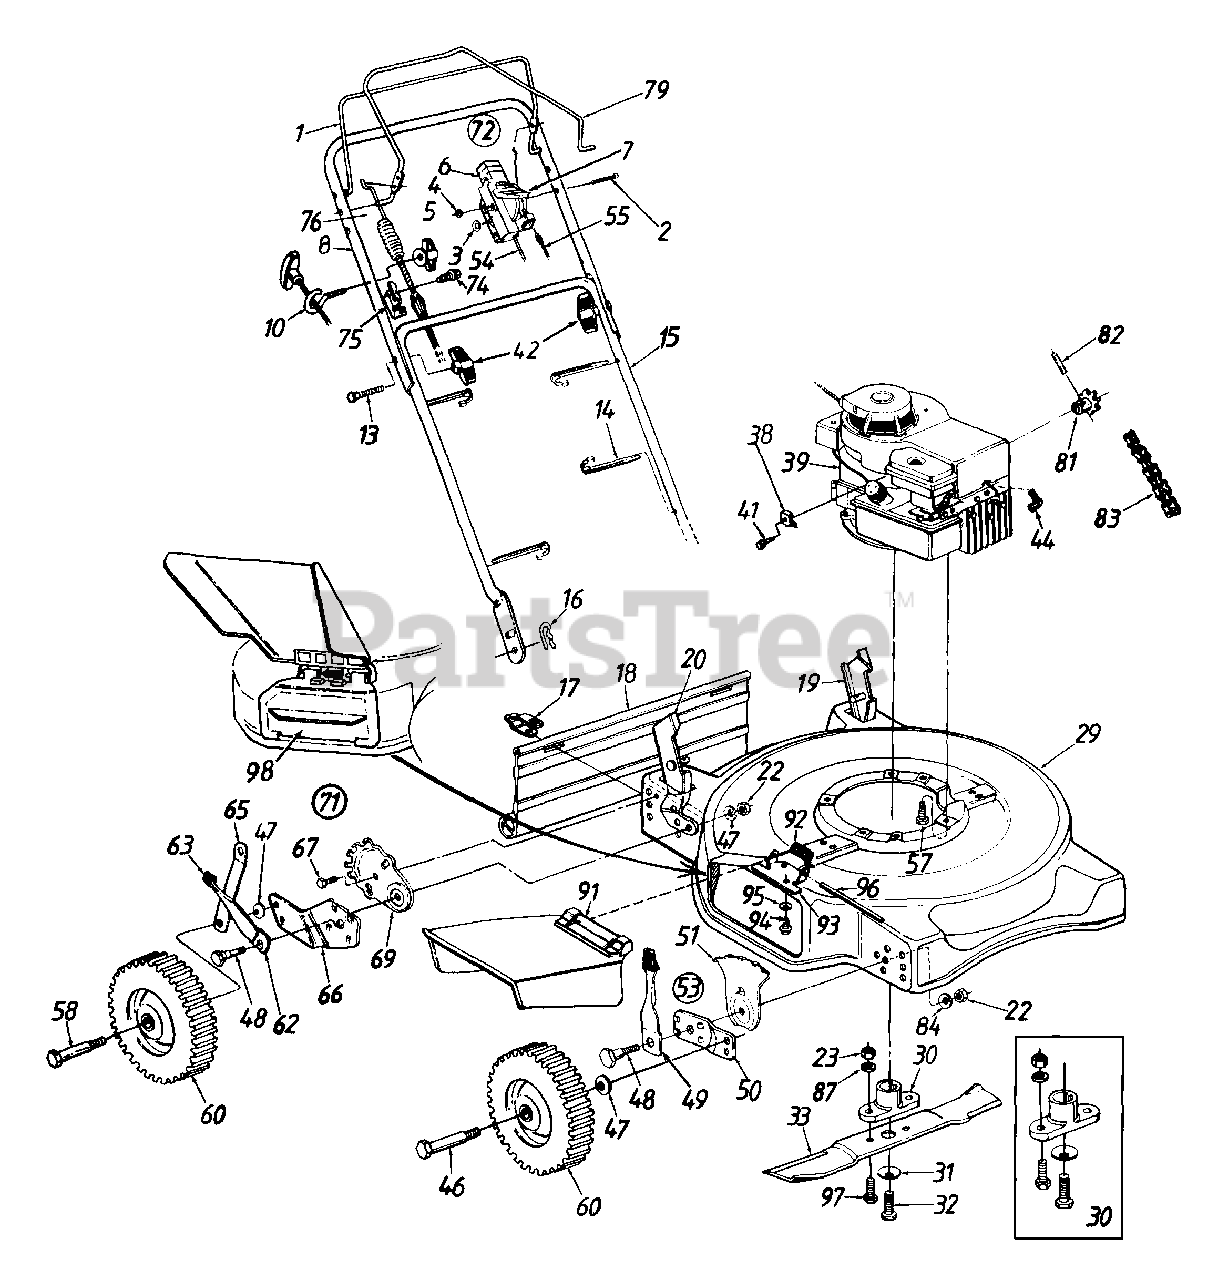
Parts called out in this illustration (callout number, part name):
2	Oval C-Sunk Mach. Scr.
3	Spr. Wash. .66" I.D.
4	Hex L-Nut 1/4 - 20 Thd.
5	Handle Knob 1/4 - 20 Thd.
6	Throttle Body
7	Throttle Lever
13	Curved Hd. Bolt 5/16 - 18 x 2" Lg.
14	Cable Tie
16	Hairpin Cotter
17	Hinge Clip
18	Rear Flap
23	Hex Nut 3/8-24 Thd.
29	22" Deck Ass'y.
30	Blade Adapter Kit
31	Bell-Wash. .39" I.D.
32	Hex Bolt 3/8-24 x 1.5" Lg.
33	22" Blade
38	Cable Clamp (B & S)
39	Engine
41	Hex Wash. Hd. Scr. #10 - 32 x .62" Lg. (B & S)
42	Hand Knob
44	Spark Plug Boot
46	Front Axle Bolt
47	Bell-Wash. .400" I.D. x .88"
48	Shld. Bolt .50" Dia. x .357"
49	Spring Lever Ass'y. w/Knob
51	Height Adj. Plate
53	Height Adj. Ass'y. Comp. - R.H.
54	Throttle Control Wire - 51" Lg. (B & S)
55	Control Cable - 39" Lg. (B & S)
57	Hex L-Wash. Hd. Scr. 3/8-16 x 1.0" Lg.
58	Rear Axle Bolt
60	Wheel Ass'y. Comp.
62	Spring Lever
63	Spring Lever Knob
67	Hex L-Wash. Hd. AB-Tap 1/4 - .62" Lg.
69	Index Plate
71	Rear Height Adj. Ass'y. - R.H.
72	Throttle Box Comp.
74	Hex Wash. AB-Tap Scr. 5/16 x .75" Lg.
75	Cable Brkt.
76	Clutch Cable
82	Spring Pin Spir 3/16" Dia. x 1" Lg.
83	#48 Chain 1/2" Pitch 50 Links (Endless)
84	Bell-Wash. .39" I.D. x 1.38"
87	L-Wash. 3/8" I.D.
91	Chute Deflector Ass'y.
92	Torsion Spring
93	Adapter Plate
94	Hex Self-Tap Scr. 1/4 - 20 x .5" Lg.
95	Bell-Wash. 1/4" I.D.
96	Hinge Pin
97	Hex Bolt 3/8 - 24 x 1" Lg.
98	Mulching Plug
